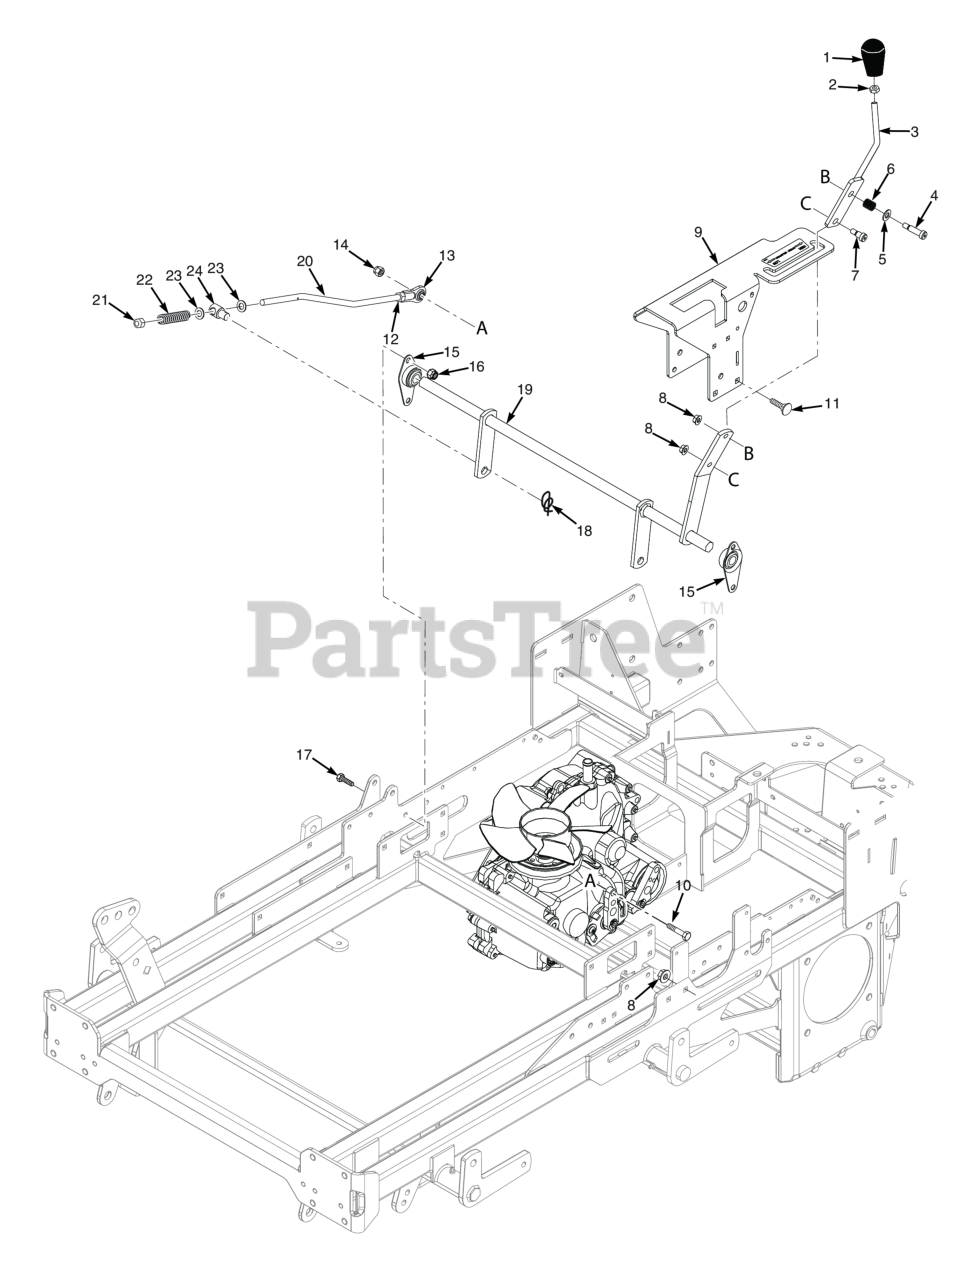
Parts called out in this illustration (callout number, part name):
1	Knob, Soft Touch
2	HEX NUT, JAM 3/8-16
3	Lever Weldment, Speed Control SCZII
4	Bolt, Shoulder 3/8 x 1"
5	Flatwasher, 3/8 (.406 x .812 x .065)
6	Spring, Speed Control Slide
7	Bolt, Shoulder 3/8 x .375"
8	Nut, Serrated Flange 5/16-18 (Right Front Engine Mounting, Briggs and Kohler Only)
9	Control Weldment w/ Decal
10	Bolt, 5/16 - 18 x 1 - 1/4" Hex Head
11	Bolt, 5/16-18 x .75 RHSN Carriage
12	HEX NUT, 3/8-24 R.H. THREAD
13	Rod End, 3/8-24
14	Nut, Center Lock, 5/16-18(32)
15	Bearing, Self Align
16	Nut, Flange Head Elastic Stop 5/16-18
17	BOLT, SERRATED FLANGE HEX HEAD 5/16-18 X 3/4"
18	Pin, Rue Cotter 1/2" Dia.
19	Speed Control Bellcrank Weldment
20	Speed Linkage Assembly (INCL. 12,13,21,22
21	Nut, Elastic Stop 3/8-24
22	Spring, Brake
23	FW, .375-.376/.380 X .734 X .063
24	BUSHING, PIVOT SLIDE
